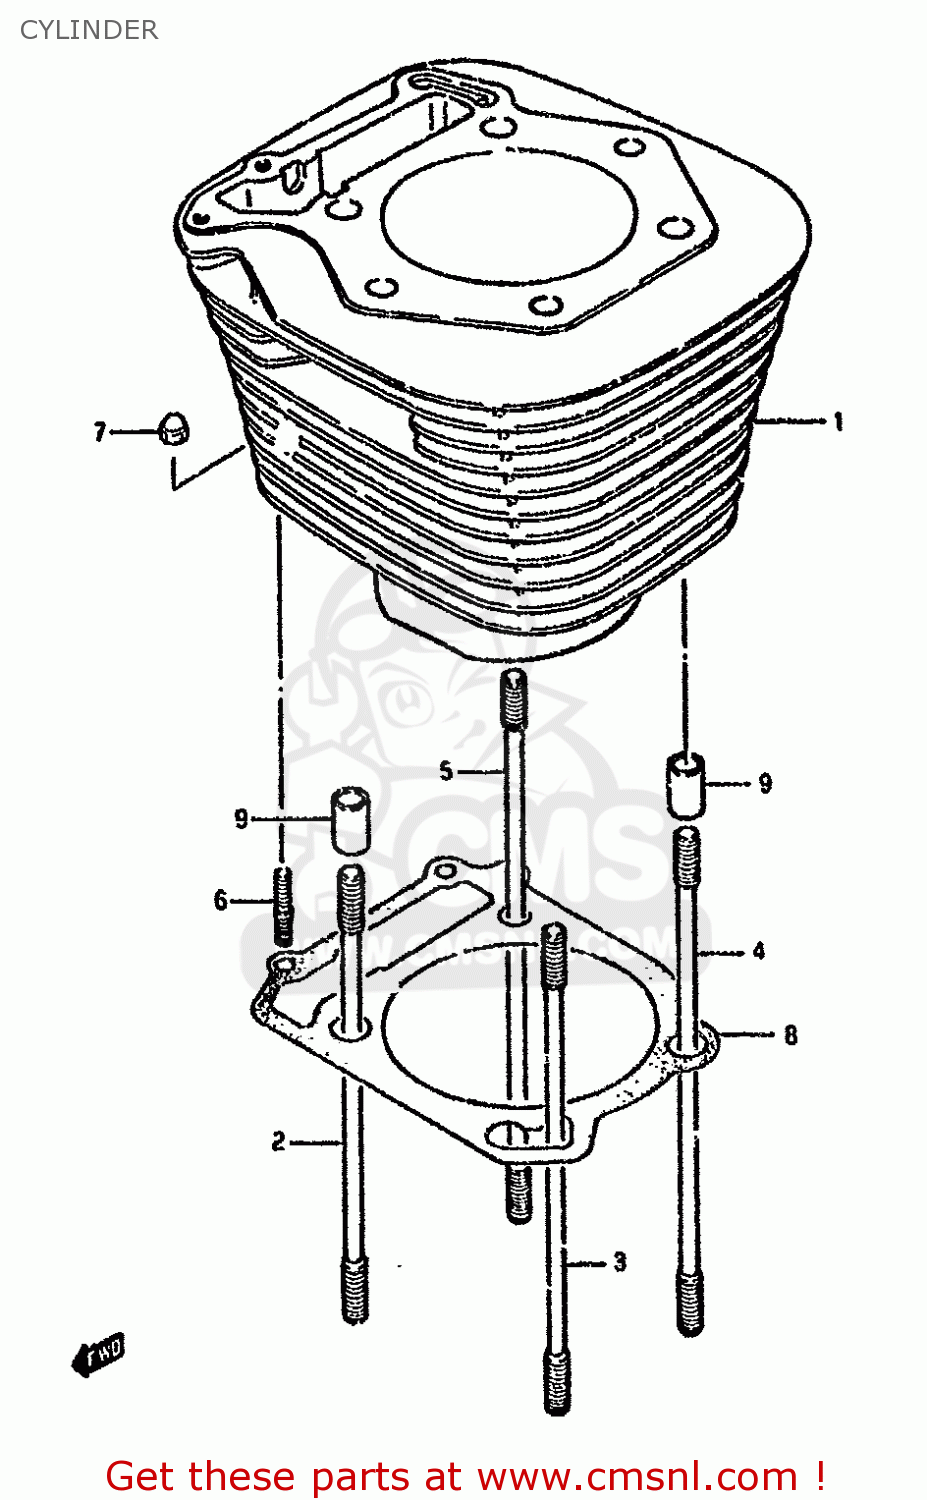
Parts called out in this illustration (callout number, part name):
1	CYLINDER
2	BOLT,STUD
3	BOLT,STUD
4	BOLT,STUD
5	BOLT,STUD
6	STUD 6X20
7	NUT
8	GASKET,CYLINDER (NAS)
9	PIN
